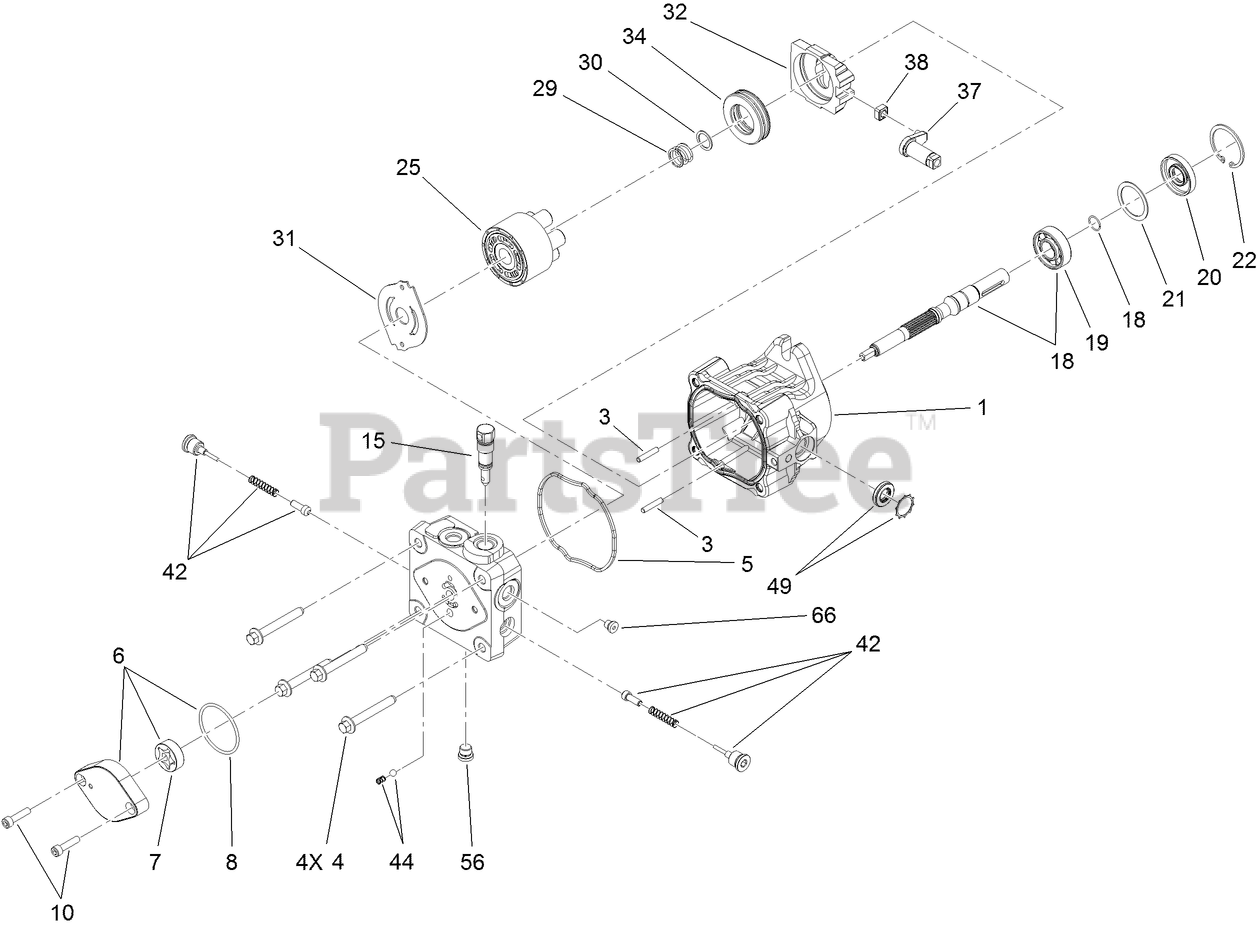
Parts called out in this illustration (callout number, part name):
1	HOUSING KIT
3	PIN-HEADLESS, STRAIGHT
4	BOLT-HF
5	O-RING
6	CHARGE PUMP KIT
7	GEROTOR ASM
8	O-RING
10	CAPSCREW
15	BYPASS VALVE KIT
18	INPUT SHAFT KIT
19	BEARING-BALL
20	SEAL-LIP
21	SPACER
22	RING-RETAINING
25	CYLINDER BLOCK KIT
29	SPRING-BLOCK
30	WASHER-THRUST
31	Plate-Valve
32	SWASHPLATE-VARIABLE
34	BEARING-THRUST
37	ARM-TRUNNION, TAPERED SQUARE
38	GUIDE-SLOT
42	VALVE-CHECK (W/POPPET)
44	CHARGE RELIEF VALVE KIT
49	TRUNNION SEAL KIT
56	PLUG-HSH
66	PLUG-HSH
